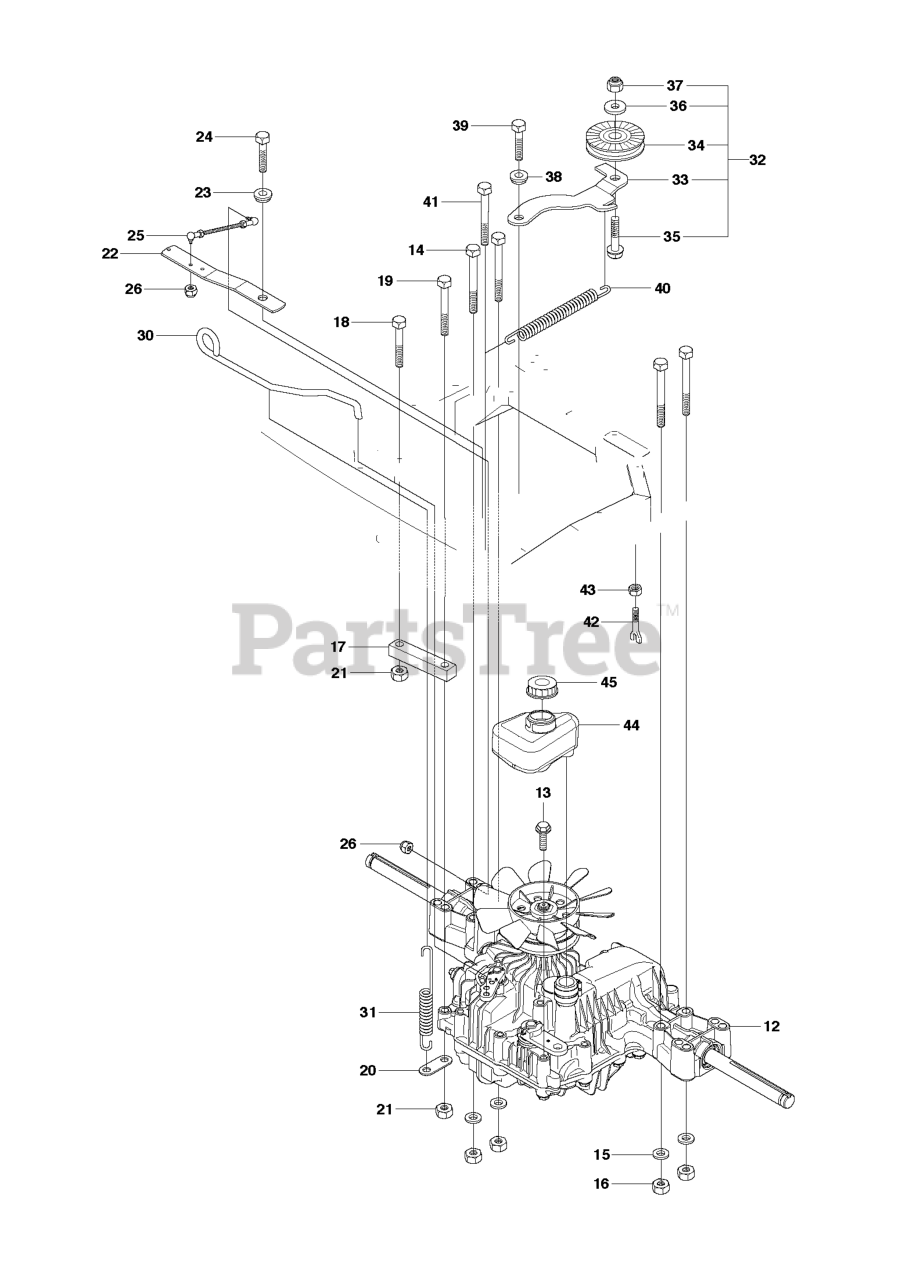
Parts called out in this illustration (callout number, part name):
12	HYDROSTAT 7A646024070
15	WASHER BRB 8.4X17
16	NUT
21	NUT
23	WASHER
24	SCREW 8X20
26	LOCKNUT M5
33	TENSIONER
35	SCREW
37	LOCKNUT M8
38	WASHER
39	SCREW 8X20
43	NUT
45	TANK CAP
